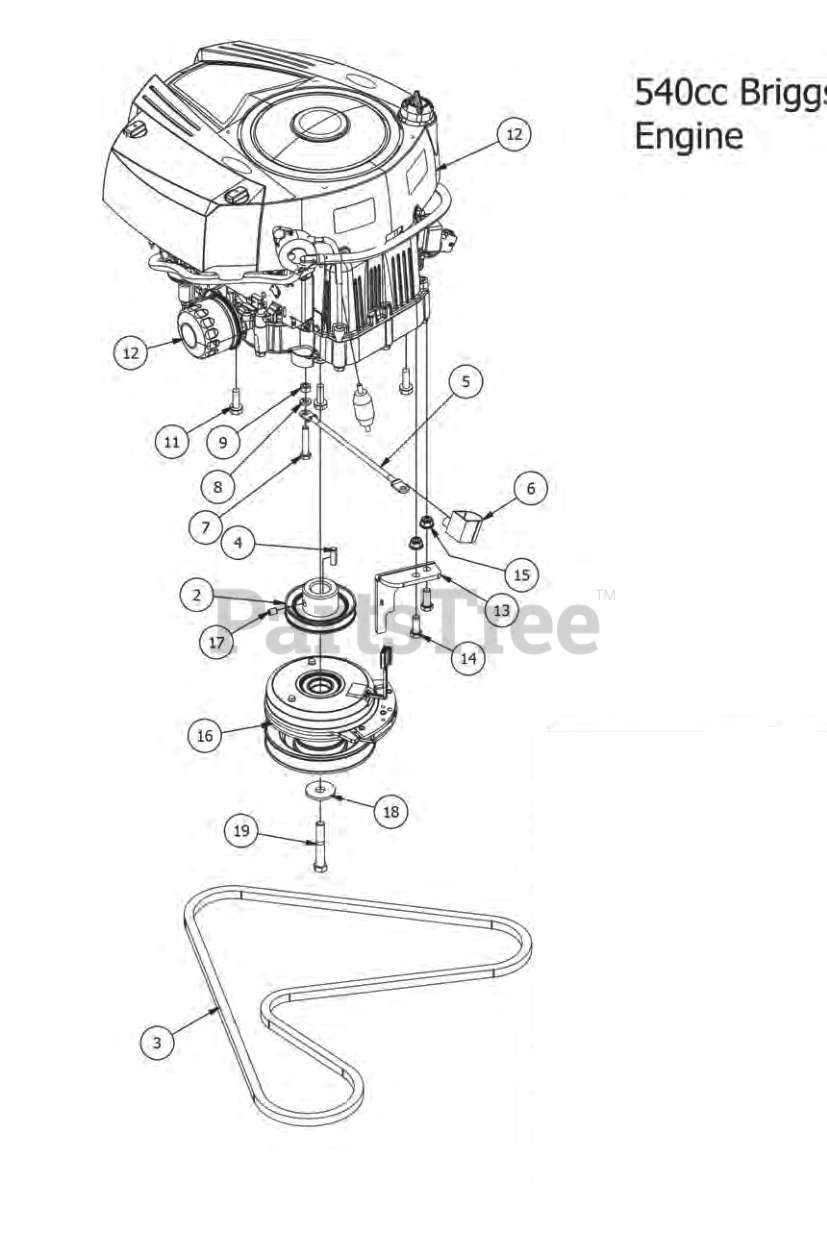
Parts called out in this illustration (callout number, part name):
2	3-3/4" Motor Pulley
4	1/4" x 1" Key
5	Ground Cable
6	Black Boot For ground cable
7	5/16" x 1 3/4" Hex Bolt
8	5/16" Lock Washer
10	Universal inline Fuel Filter
11	3/8 x 1 1/8 bolt
12	540cc Briggs Intek Engine-MZ
13	Warner Clutch A-R Bracket
14	3/8" x 1" Hex Bolt
15	3/8" Nylock Flange Nut
16	Clutch 2015 Magnum/MZ
17	3/8" Set Screw
18	1/2 Belleville Washer
19	7/16" x 2 3/4" Fine Thread Bolt
20	Briggs Oil Filter
